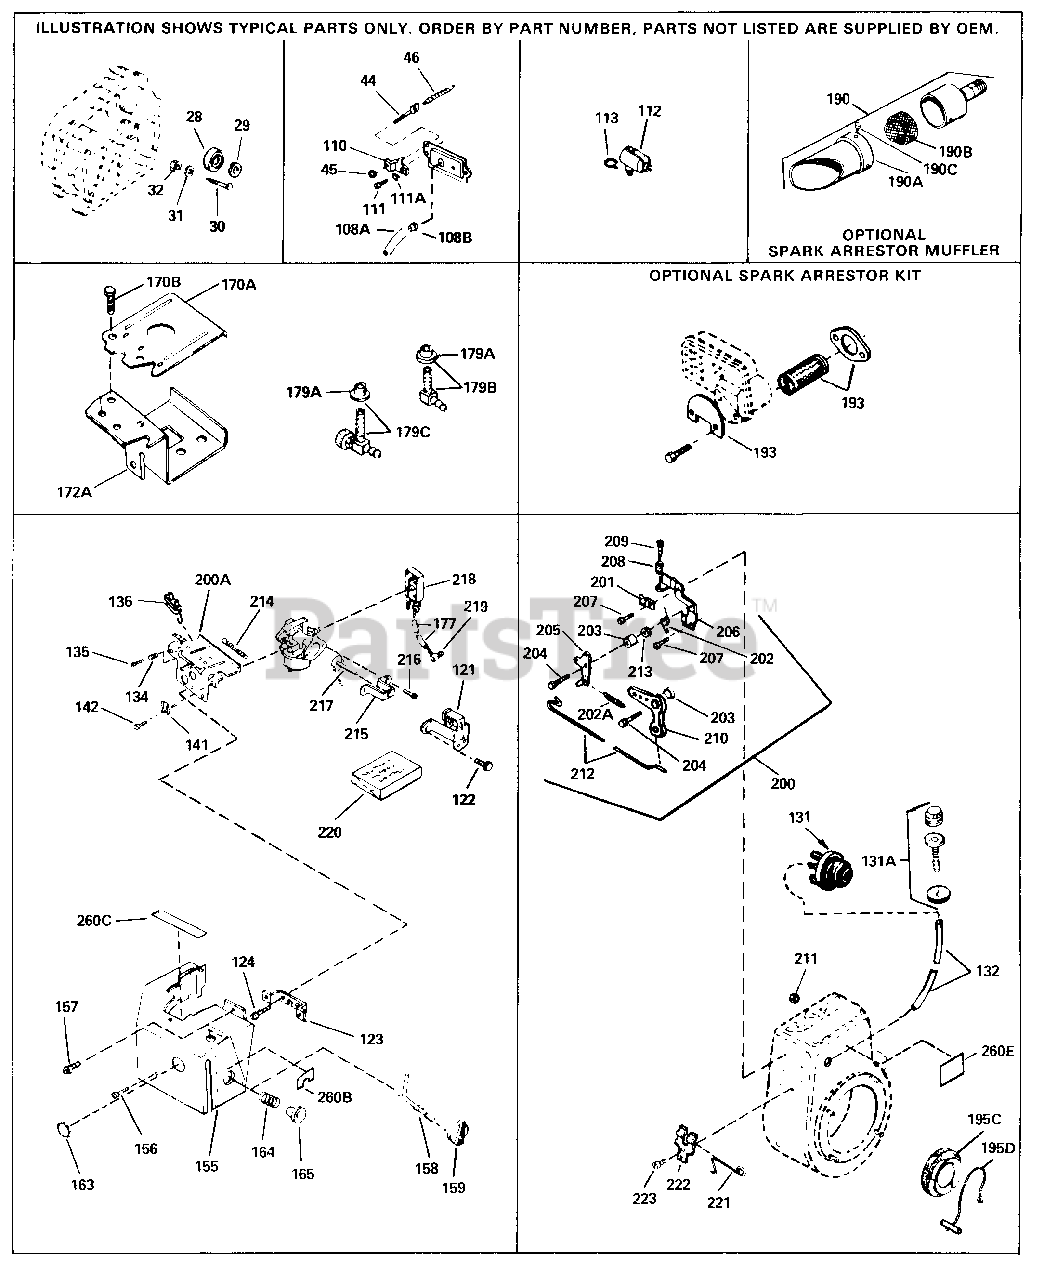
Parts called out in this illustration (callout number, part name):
28	Bearing, Ball
29	Washer, Thrust
30	Retainer, Bearing
31	Nut, Lock, 10-24
32	Nut, Lock, 10-23
98	Screw, 5/16-18 x 1-1/2" Use as requir ed, but do notuse No. 650691 washer.
98	Screw, 5/16-18 x 1-3/4" Use as requir ed
98	Screw, 5/16-18 x 1-5/8" (Use as requi red) (Can use No. 6021A but discard N o. 650691 washer.)
124	Screw, 8-32 X 27/64``
134	Spring, Compression
135	Screw, 5-40 x 7/16"
136	Terminal Assy. (Use as required)
158	Rod, Choke
170A	Plate, Upper fuel tank, mtg.
170B	Screw, T-30, 1/4-20 x 1/2"
172A	Bracket Assy., Lower fuel tank mtg.
177	Fuel Line (8.62") 21 cm)
177	Fuel Line (Use as required) (16.0") 41 cm
179A	Bushing, Fuel fitting
179C	Fuel Fitting (Incl. 179A)
190	Muffler (Incl. 190A, 190B & 190C) (Th is spark arrestor mufflercan be used on any model)
190A	Cover & Tube, Muffler Use as require d
190B	Screen, Muffler (Use as required)
190C	Screw, 8-18 x 3/8" (Use as required)
193	Spark Arrestor Kit Fits "L" shaped m ufflers
200A	Control Bracket Incl. 134, 135, 136 & 214
201	Conduit Clip
214	Spring, Governor extension
260B	Decal, Air cleaner
